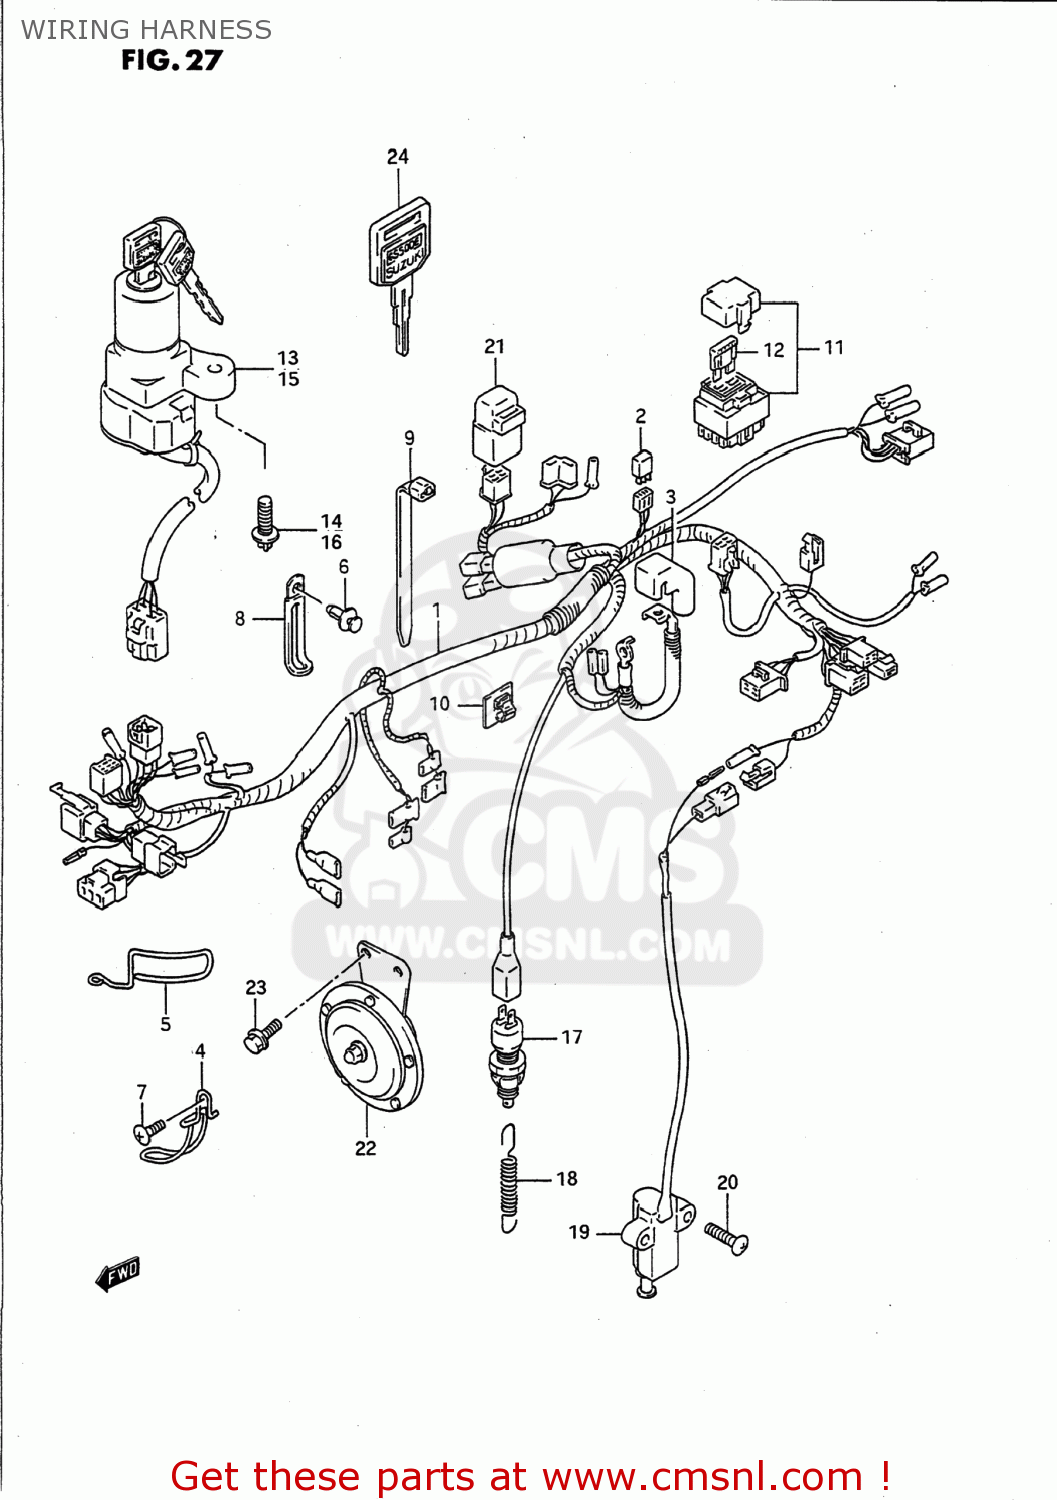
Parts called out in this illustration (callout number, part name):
1	HARNESS,WIRING
2	DIODE(STANLEY DE8804)
3	CAP,BATTERY PLUS
4	PROTECTOR
5	PROTECTOR
6	CLIP
7	SCREW 6X12
8	CLAMP
9	CLAMP L:165
10	CLAMP
11	BOX ASSEMBLY,FUSE
12	FUSE(20A)
13	LOCK ASSEMBLY,STEERING
14	SCREW(6X18)
15	LOCK ASSEMBLY,STEERING
16	SCREW(6X18)
17	SWITCH ASSY,STOP LAMP
18	SPRING
19	SWITCH ASSY,SIDE STAND
20	BOLT
21	RELAY ASSY
22	HORN ASSY
23	BOLT
24	KEY,BLANK
